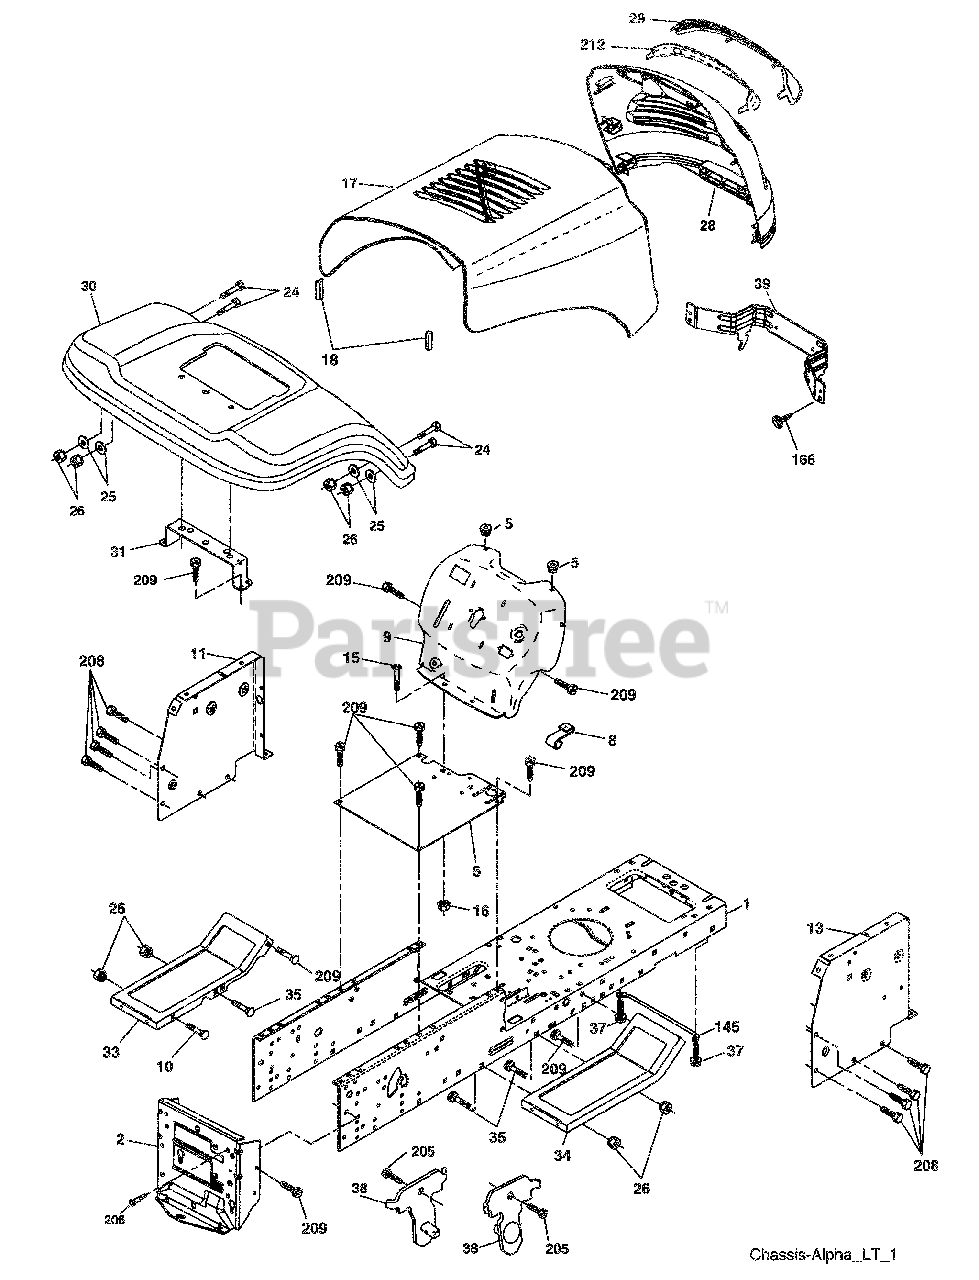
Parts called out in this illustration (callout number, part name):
1	Chassis
2	Drawbar, Stretch
5	Bumper, Hood/Dash
6	Saddle
8	Clip Retainer Slide-On
9	Dash
10	Bolt, Carriage 3/8-16 x 1
11	Panel Dash LH
13	Panel Slkscr Dash RH
15	Screw Mach TRHD 5/16-18 unc x 3/4
16	Nut Keps 5/16-18 unc
17	Hood
18	Bumper Hood
24	Bolt Fin Hex 3/8-16 unc x 1 Gr. 5
25	Washer 13/32 x 13/16 x 12 Ga.
26	Nut Lock Hex w/lns 3/8-16 unc
28	Grille/Lens Asm.
29	Lens Grille Bar
30	Fender
31	Bracket Fender Repl 109873X
33	Footrest Pnt LH
34	Footrest Pnt RH
35	Bolt Rdhd Sht Sqnk 3/8-16 x 3/4
37	Screw Thdrol 5/16-18 x 1/2 TYT
38	Bracket Asm. Pivot Mower
39	Bracket Pivot
145	Rod Pivot Chassis/Hood
205	Screw Thdrol 3/8-16 x 1/2
206	Bolt Shoulder 5/16-18
208	Screw Thdrol 3/8-16 x 1/2
209	Screw Hex Wsh Thdrol 3/8-16
212	Insert Lens Reflect
278	Screw 10 x 3/4 Single Lead Hex
278	Plug Button Blk 359 Dia Choke
278	Plug Dome Plastic
